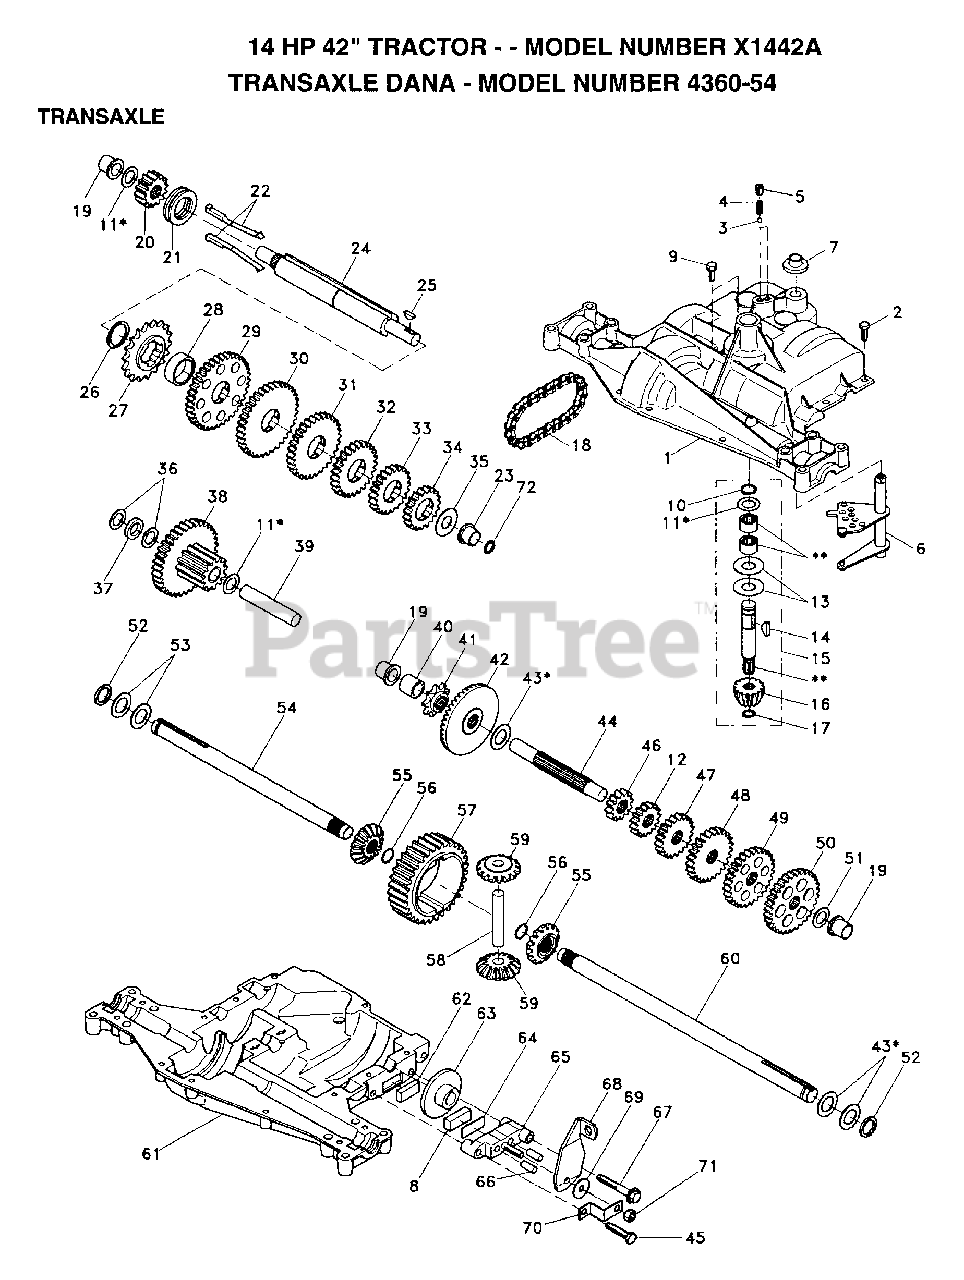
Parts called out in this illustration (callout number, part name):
4	"SPRING, DETENT LT"
5	"SCREW, SET LT"
6	SHIFTER.ASM.KIT.
7	SHIFTER BOOT
8	PUCK T
9	SCREW TAP W/SEAL
10	RETAINING RING LT
11	ASM KIT SHIM 4689
13	WASHER T
14	WOODRUFF KEY
17	"RING,RETAINING LT"
18	"CHAIN,24 PTCH LT"
19	BEARING.FLNG.5510
20	GEAR SPUR 14T
21	COLLAR CLUTCH
22	KIT.ASM.CLUTCH KY
23	"FLANGE, BEARING"
24	SHAFT INTERM
25	WOODRUFF KEY
26	"RING,RETAINING LT"
27	SPROCKET 18T T
28	SPACER YT
29	KIT.GEAR.12/37TH
31	GEAR SPUR 30T
32	GEAR 25T LT
33	GEAR SPUR 22 TT
34	SPUR GEAR 19T
35	"WASHER, PLAIN LT"
36	WASHER 025
37	SPACER
38	ASSM GEAR COMB
39	SHAFT IDLER
40	SPACER T
41	SPROCKET 9T LT
43	ASM KIT SHIM
44	SHAFT T
45	"SCREW, TAPPING LT"
48	"GEAR, SPUR 25T LT"
49	GEAR 28T T
50	"GEAR, SPUR 31T LT"
51	WASHER 060
52	NEOPRENE WASHER
53	WASHER 031
55	GEAR LT
56	"RING,RETAINING LT"
58	SHAFT T
59	SHAFT T
62	PUCK T
63	BRAKE DISC. T
64	SPACER LT
66	PIN T
69	WASHER LT
71	NUT.LOCK.5/16-24
72	SQUARE RING
